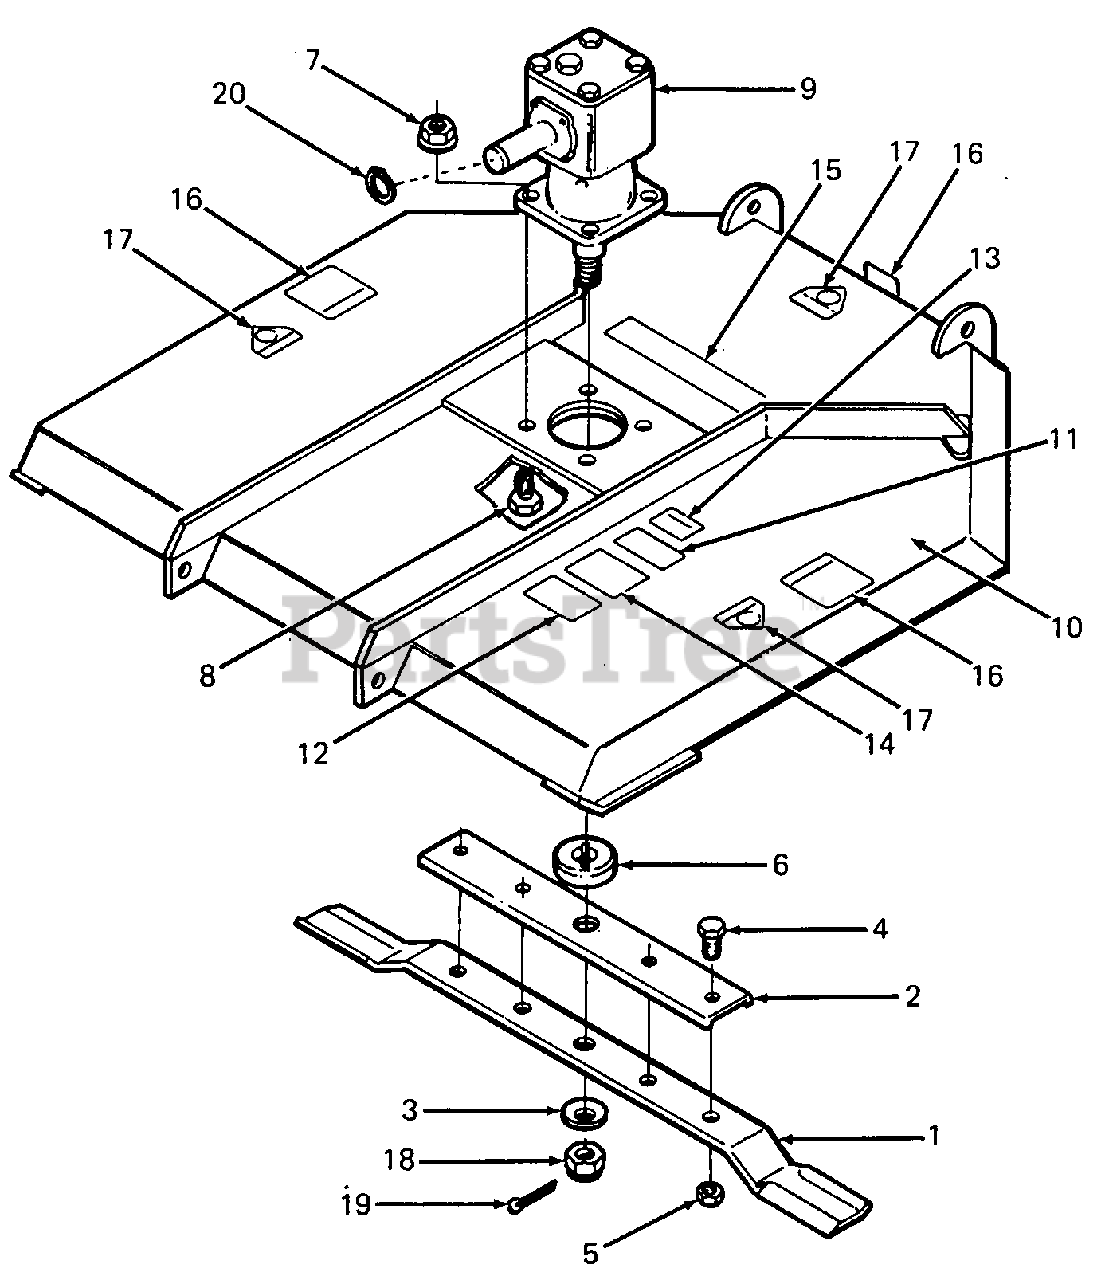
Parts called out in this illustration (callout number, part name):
2	Blade Support
3	Washer, Spring
4	Capscrew, 3/8 X 1"
5	Locknut, 3/8
7	Locknut, Flanged, 5/8
8	Capscrew, 5/8 X 1-3/4"
9	Gearbox Assy
10	Base w/Decal
11	Decal, Warning
12	Decal, Danger
13	Decal, Caution
14	Decal, Warning
15	Decal, Cub Cadet Logo
16	Decal, Thrown Object
17	Decal, Danger
18	Nut, Castle
19	Pin, Cotter
20	Ring, Snap
